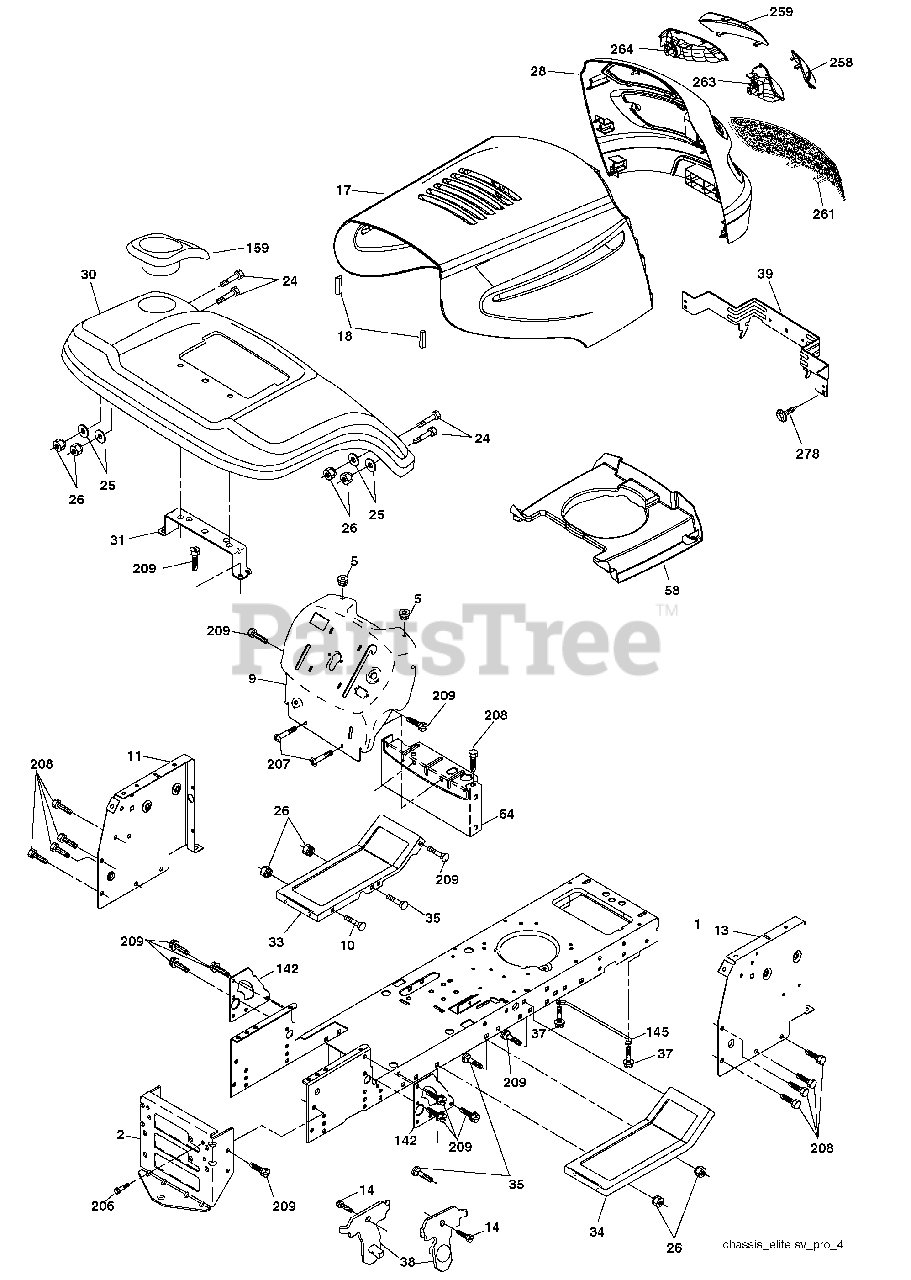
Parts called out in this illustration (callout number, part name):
1	Chassis
2	Drawbar
5	Bumper Hood/Dash
9	Dash P/L
10	Bolt Carriage 3/8-16 x 1
11	Panel Dash Lh
14	Screw Thdrol 3/8-16 x 1/2
17	Hood
18	Bumper Hood
24	Bolt Fin Hex 3/8-16 unc x 1 Gr. 5
25	Washer 13/32 x 13/16 x 12 Ga.
26	Nut Lock Hex W/Ins 3/8-16 unc
28	Grille/Lens Asm
30	Fender
31	Bracket Fender
33	Footrest LH
34	Footrest RH
35	Bolt RDHD SHT SQNK 3/8-16 x 3/4
37	Screw Thdrol 6/16-18 x 1/2 TYT
38	Bracket Asm Pivot Mower Rear
39	Bracket Pivot
58	Duct Air
64	Dash Lower STLT
142	Plate Reinforcement STLT
145	Rod Pivot Chassis/Hood
159	Cupholder
206	Bolt Shoulder 5/16-18
207	Screw Thdrol 5/16-18 x 1/2
208	Screw Thdrol 3/8-16 x 1/2
209	Screw Hexwsh Thdr 3/8-16 x 3/4
258	Lens Grille Pro RH
259	Lens Grille Pro LH
263	Bezel Grille RH
264	Bezel Grille LH
278	Screw 10 x 3/4 Single Lead Hex
278	Plug BTN BlK
278	Plug Dome Plastic
